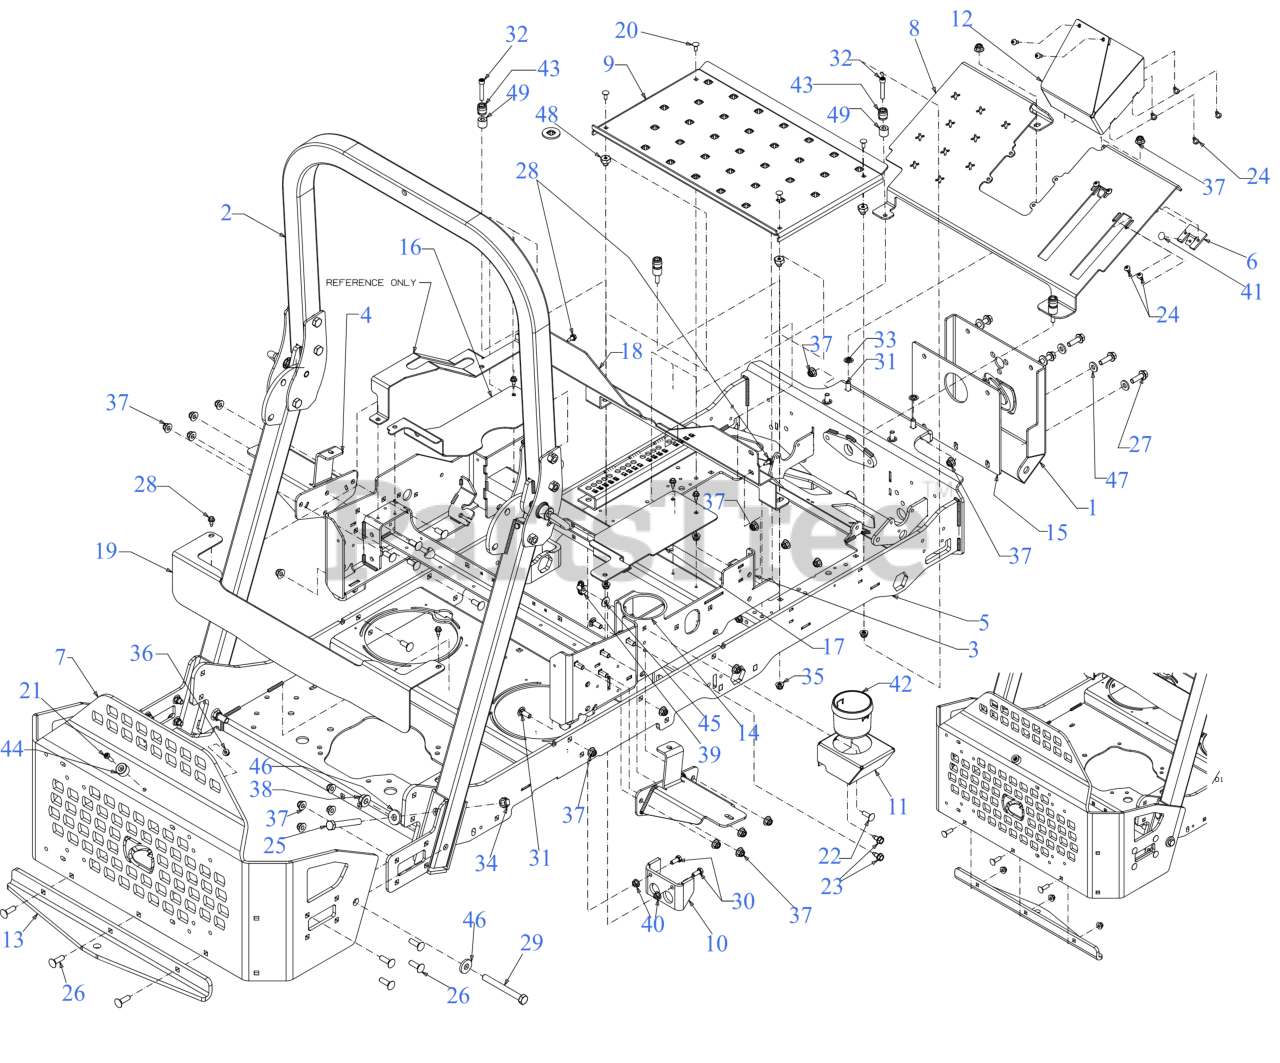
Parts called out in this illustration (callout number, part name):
2	PRO Z ROPS KIT
3	SEAT FRAME
4	FUEL TANK MOUNT
5	FRAME
6	REVERSE PEDAL STOP BRACKET
15	FRONT MOUNTING PLATE SPACER
16	SEAT COVER PANEL (LH)
17	SEAT COVER PANEL (RH)
18	SEAT BOX COVER
19	SEAT BOX COVER
20	CARRIAGE BOLT 1/4-20 x .62
21	MACHINE SCREW 1/4-20:1
22	CARRIAGE BOLT 5/16-18 x 1.00
23	SCREW 5/16-18 x .750
24	SCREW 1/4-20 x .5
25	SCREW 1/2-20 x 3.50 GR5
26	CARRIAGE BOLT 3/8-16 X1.25 GR5
27	SCREW 3/8-16 x 1.25 GR5
28	SCREW 1/4-20X.625
29	SCREW 1/2-13 x 4.5 GR 5
30	SCREW 5/16-18 x .75 GR5
31	CARRIAGE BOLT 3/8-16 x 1.00 GR5
32	SCREW 5/16-18X1.75 GR5
35	FLANGE LOCK NUT 5/16-18
36	FLANGE LOCK NUT
39	WING NUT 5/16-18
40	FLANGE NUT
41	RATCHET CLIP
43	RADIAL BUMPER
45	FLAT WASHER
46	FLAT WASHER .531 x 1.25 x .181
47	FLAT WASHER
48	SHOULDER SPACER
